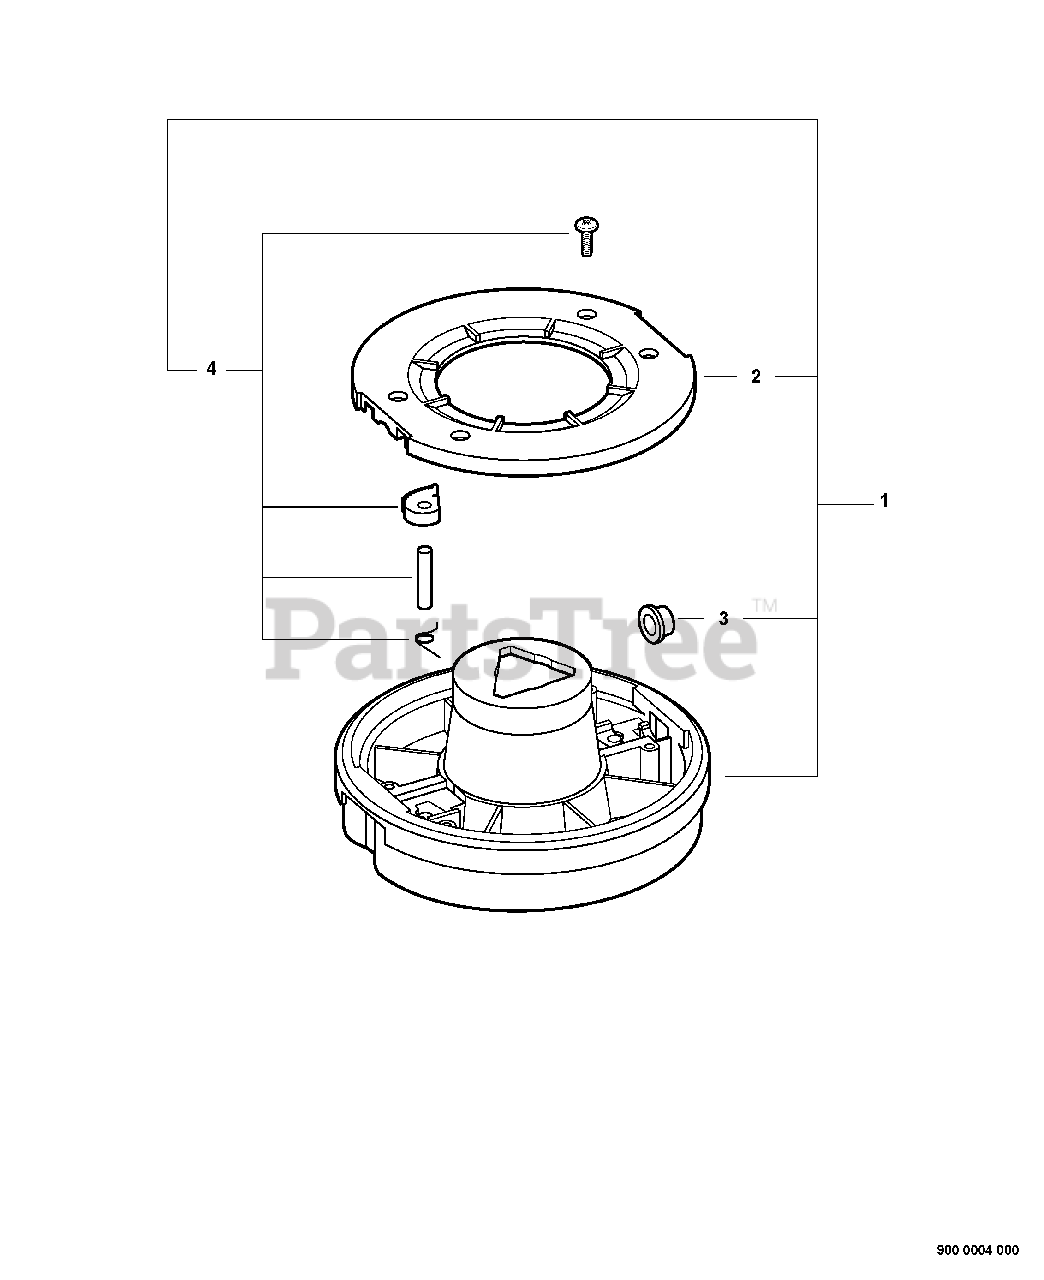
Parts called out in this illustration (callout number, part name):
1	TWO LINE RAPID LOADER HEAD
2	COVER - TOP
4	REPAIR KIT
